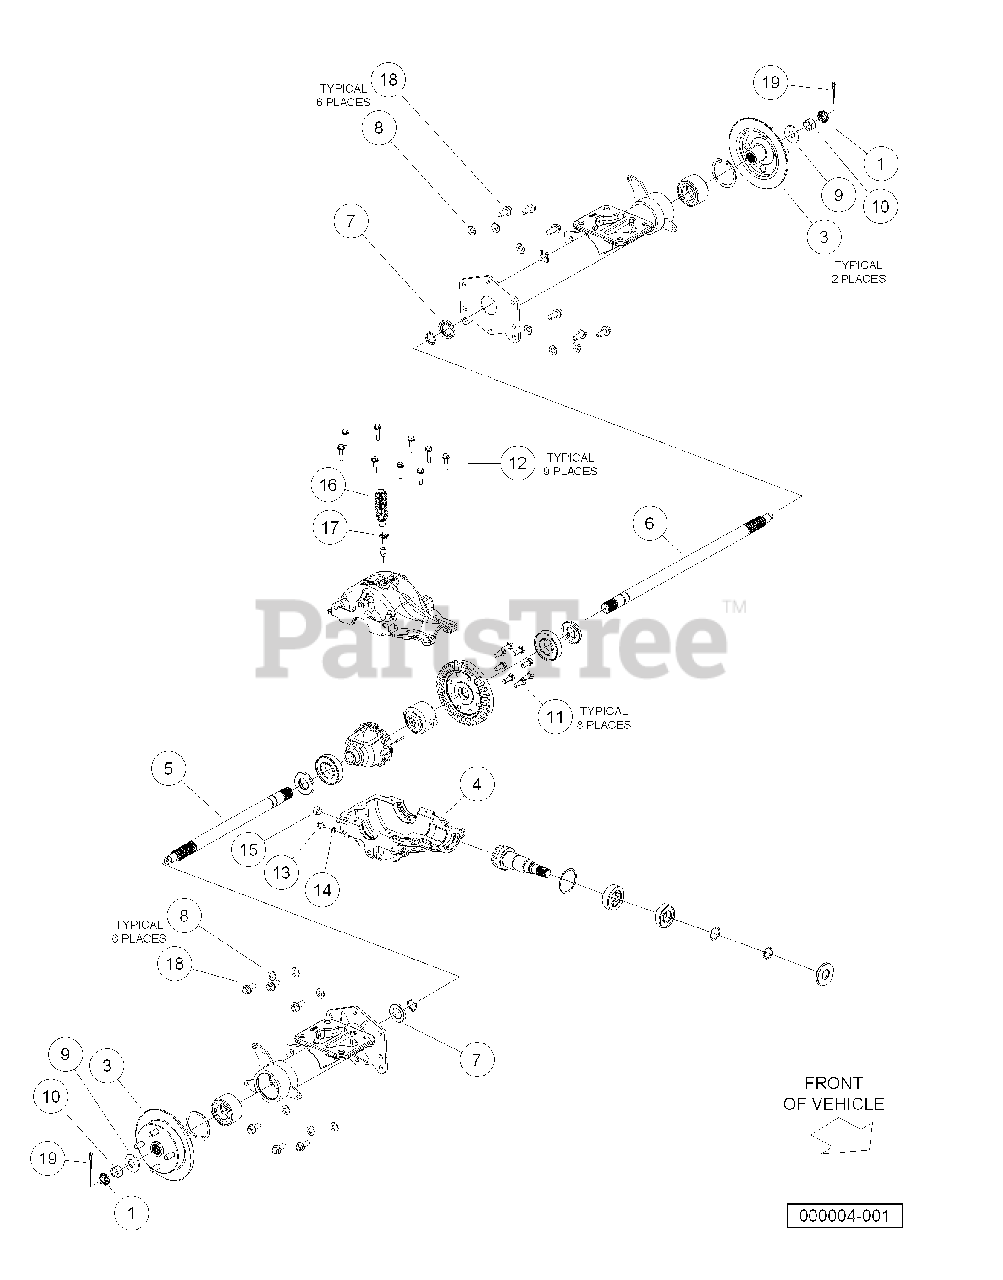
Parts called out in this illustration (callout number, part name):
1	Axle, Rear, Guard Mounts
2	Locking Cap, Nut
3	Assy, Rotor, Brake, Rear
4	Gearcase, Lower, Machined
5	Axle, Right-hand
6	Axle, Left-Hand
7	Washer,counterbored 51 X 30
8	Washer, Bellevle, 1.063 X .043
9	Washer, Belleville, 49 X 4
10	Nut, Hex, M20 X 1.5 , Modified
11	Screw, M10 X 25
12	Screw,hex Flange, M8 X 35
13	Plug,3/8-16, Hex Flange
14	Washer, .625 X .382 X .60
15	Plug, Square Skt, 1/12-14, Ptf
16	Bellows, Vent, Upper Housing
17	Clamp, Hose, Dw-9.5
18	Screw, Hex Fl, M12 X 1.75 X 30
19	Pin, Cotter, 5/32 X 1.25
